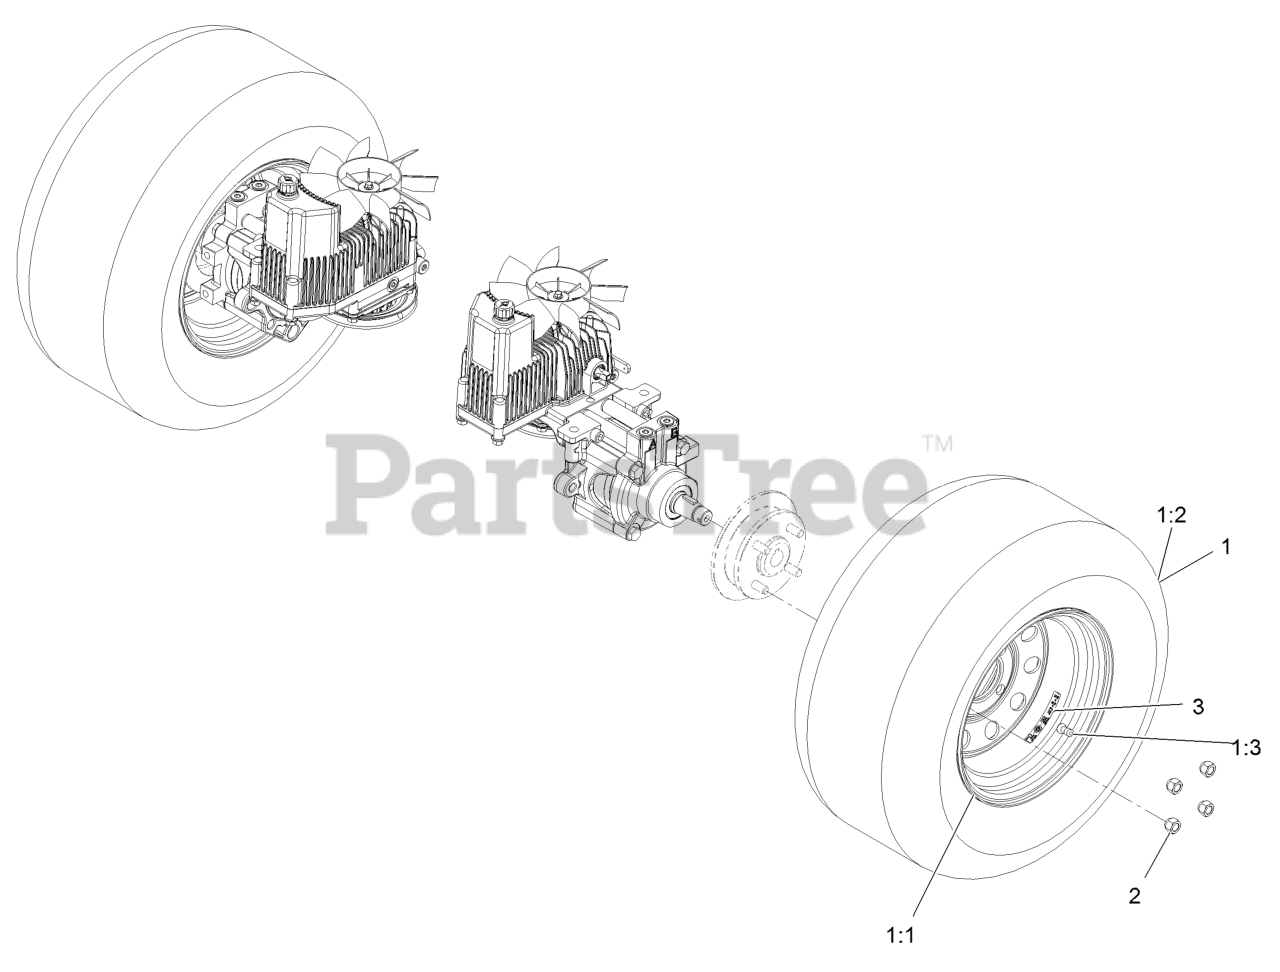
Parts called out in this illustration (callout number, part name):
1	ASM-WHEEL AND TIRE
1:1	ASM-RIM 60
1:2	TIRE-DRIVE
1:3	Stem-Valve
2	NUT-LUG
3	DECAL-TORQUE, WHEEL HUB LUG
